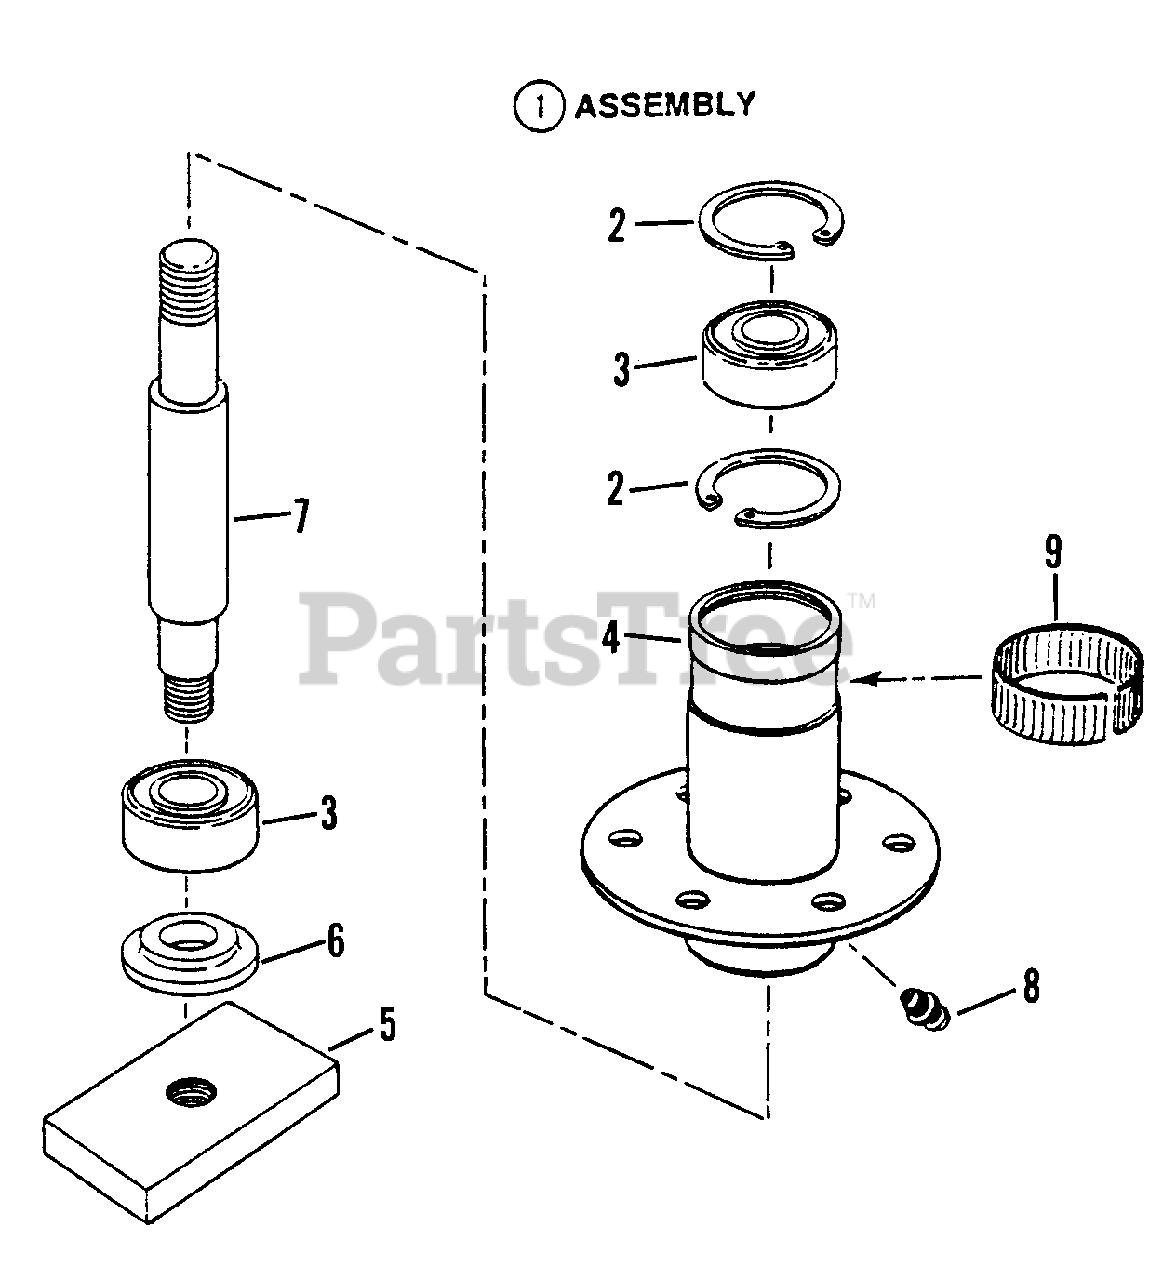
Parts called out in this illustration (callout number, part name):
1	ASSEMBLY, Spindle (Includes 2 thru 7)(48" Outboard)
1	ASSEMBLY, Spindle (Includes 2 Thru 7) (48" Center)
2	RING, Retaining EXT 1.75"
3	BEARING, Spindle
4	HOUSING, Spindle - Outboard, 4.25"
4	HOUSING, Spindle - Center, 4.59"
5	HOLDER, Blade
6	WASHER, Spindle
7	SPINDLE, 6.06" Long
7	SPINDLE, 7.25" Long
8	FITTING, Lube (Press fit for .187 hole-no ball)
9	RING, Tolerance 2.0"
